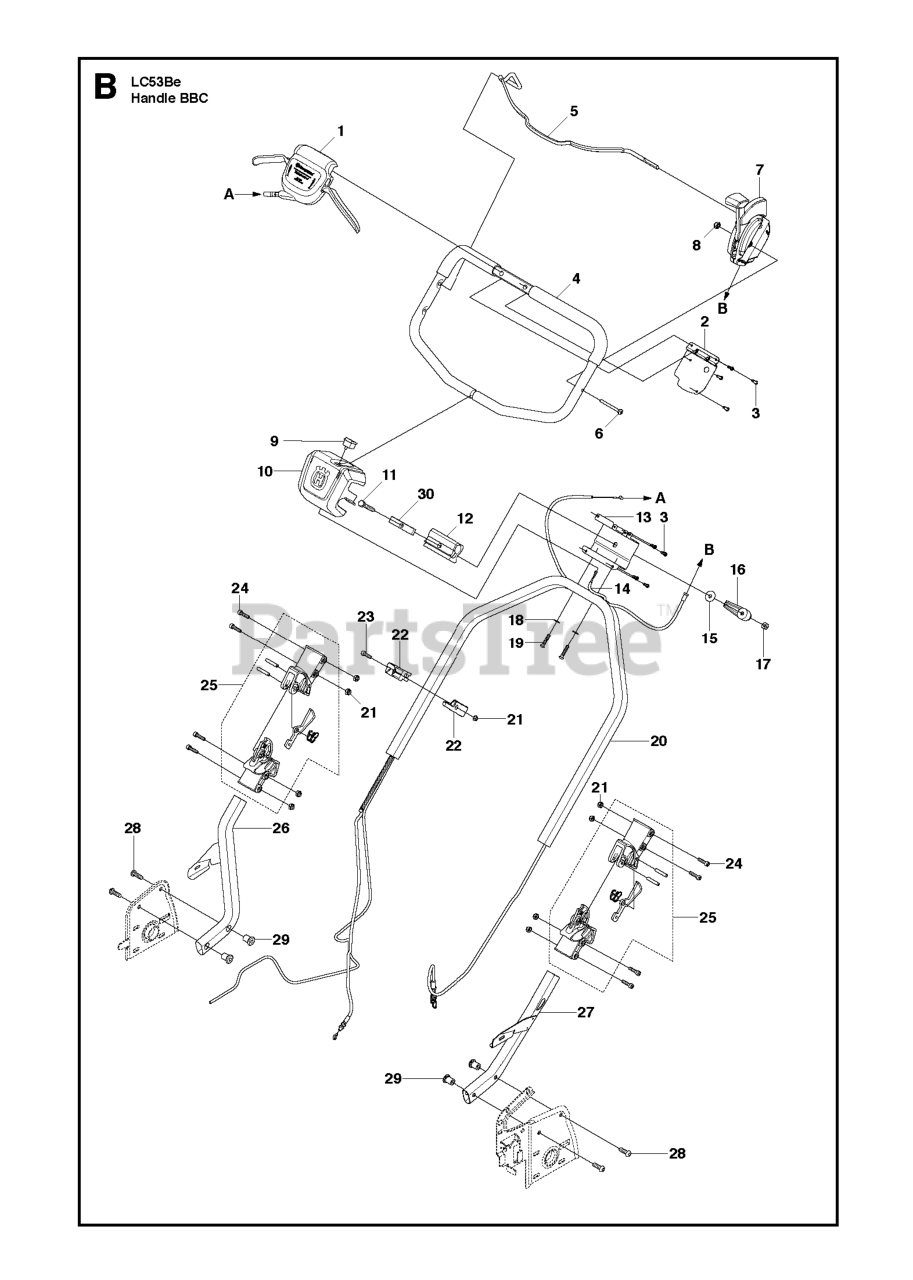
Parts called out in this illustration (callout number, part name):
15	WASHER - 25X8.5X2.3
23	SCREW MC6S 6X20
24	REPL BY 725 53 74-55
